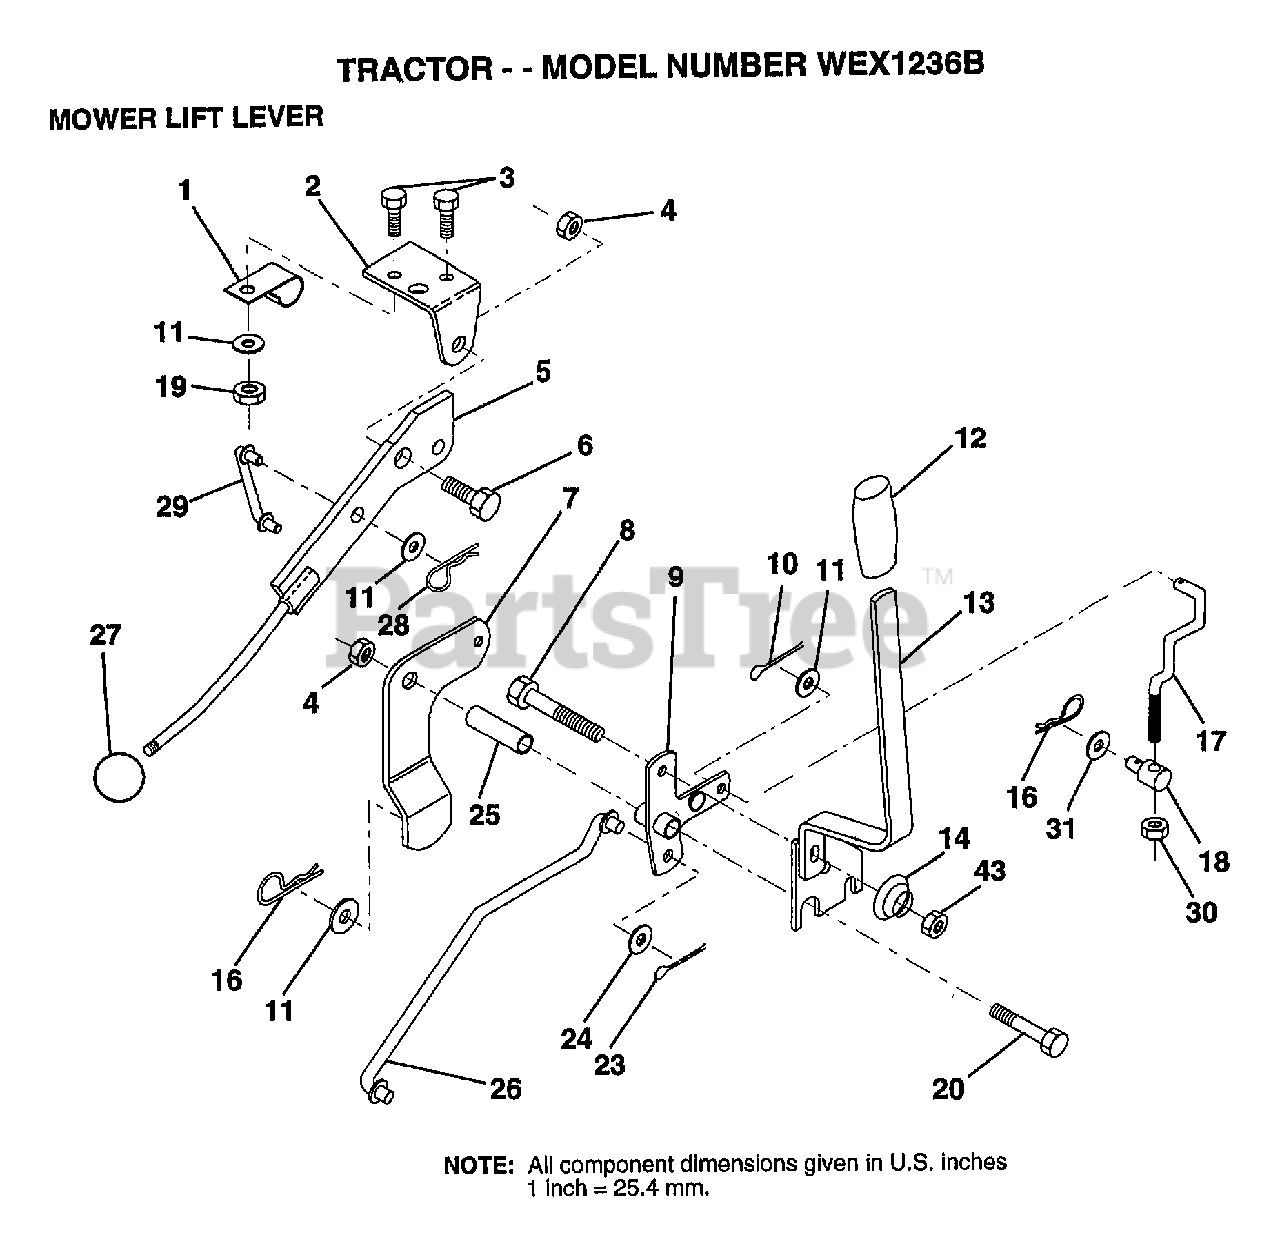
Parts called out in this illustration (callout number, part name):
1	"CLIP,INSULATOR"
2	BRKT CLUTCH
3	BOLT HXHD FIN
5	LEVER.ASM.CLUTCH
6	"BOLT, SHOULDER LT"
7	MWR CLUTCH ARM AS
8	BOLT
9	"BELLCRANK,LIFT"
10	COTTER PIN
11	WASHER
13	HANDLE.ASM.LIFT
14	SPRING COMPRESSIO
16	SPRING.RETAINER
17	"LINK,LIFT FRT"
18	TRUNION ADJ
20	BOLT
23	PIN COTTER 1/8
25	TUBE SPACER
26	ROD LIFT MOWER
27	KNOB T(3/8 HOLE)
28	RETAINER M
29	CLUTCH LINK
30	NUT
31	WASHER
